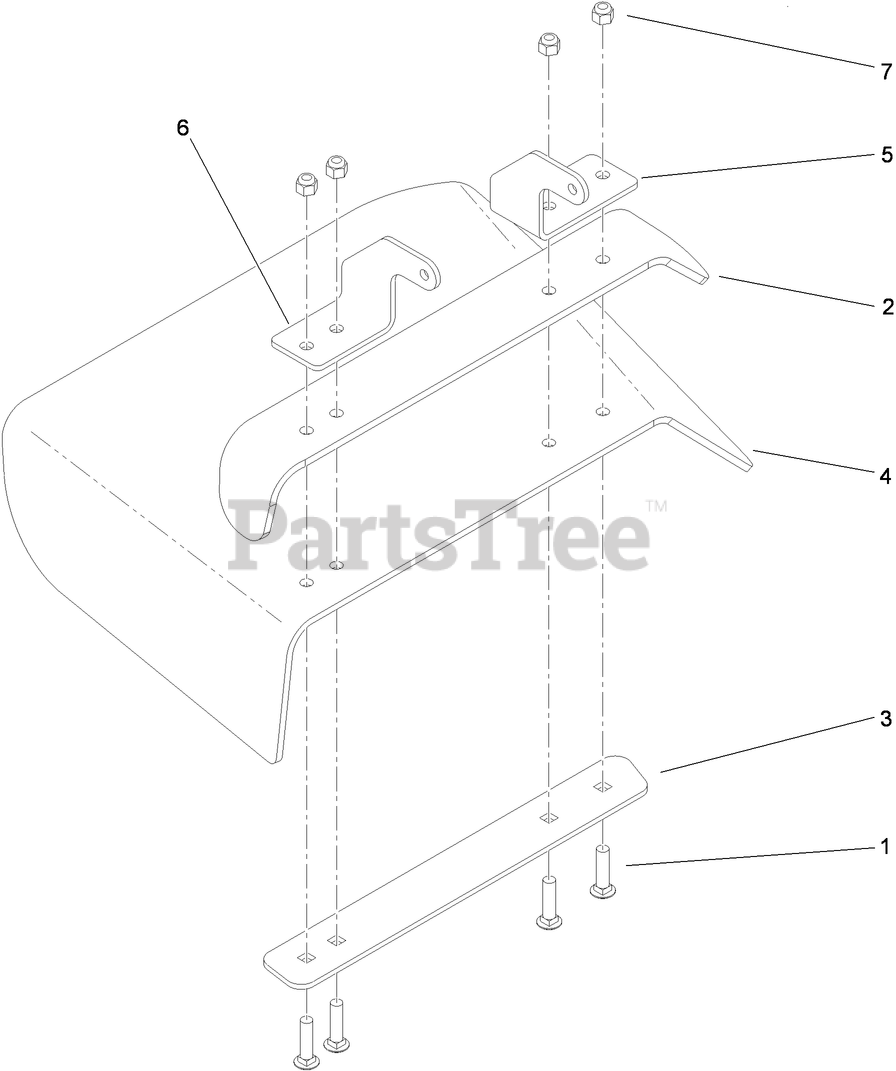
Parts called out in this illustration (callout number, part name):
1	SCREW-CARR
2	DEFLECTOR
3	STRAP-DISCHARGE
4	DEFLECTOR-RUBBER
5	BRACKET-HINGE, REAR
6	BRACKET-HINGE, FRONT
7	NUT-LOCK, NI
